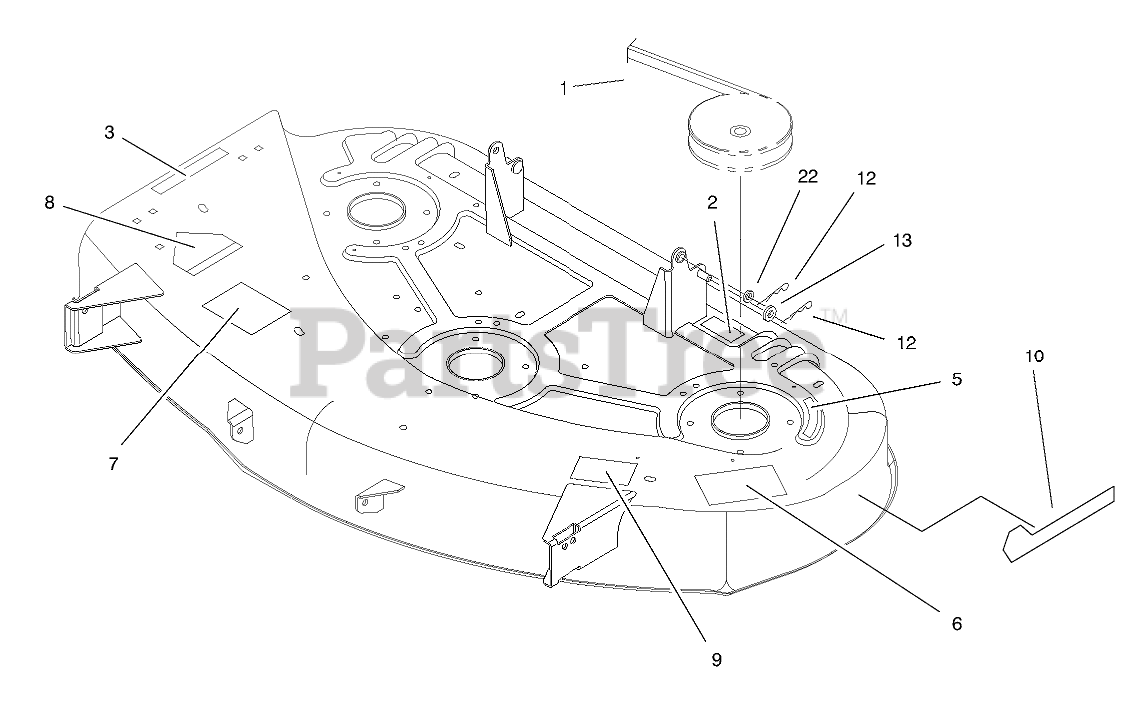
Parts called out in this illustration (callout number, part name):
1	V BELT-DECK
2	DECAL-WARNING
3	DECAL-DANGER, DEFLECTOR
5	DECAL-DANGER, SHIELD
6	DECAL-DANGER, THROWN OBJECT
7	DECAL-INSTALL, BELT
8	DECAL-DANGER
9	DECAL-ADJUSTMENT, WHEEL
10	DECAL - RECYCLER DECK
12	PIN-COTTER
13	WASHER-HARDENED
22	WASHER-FLAT
